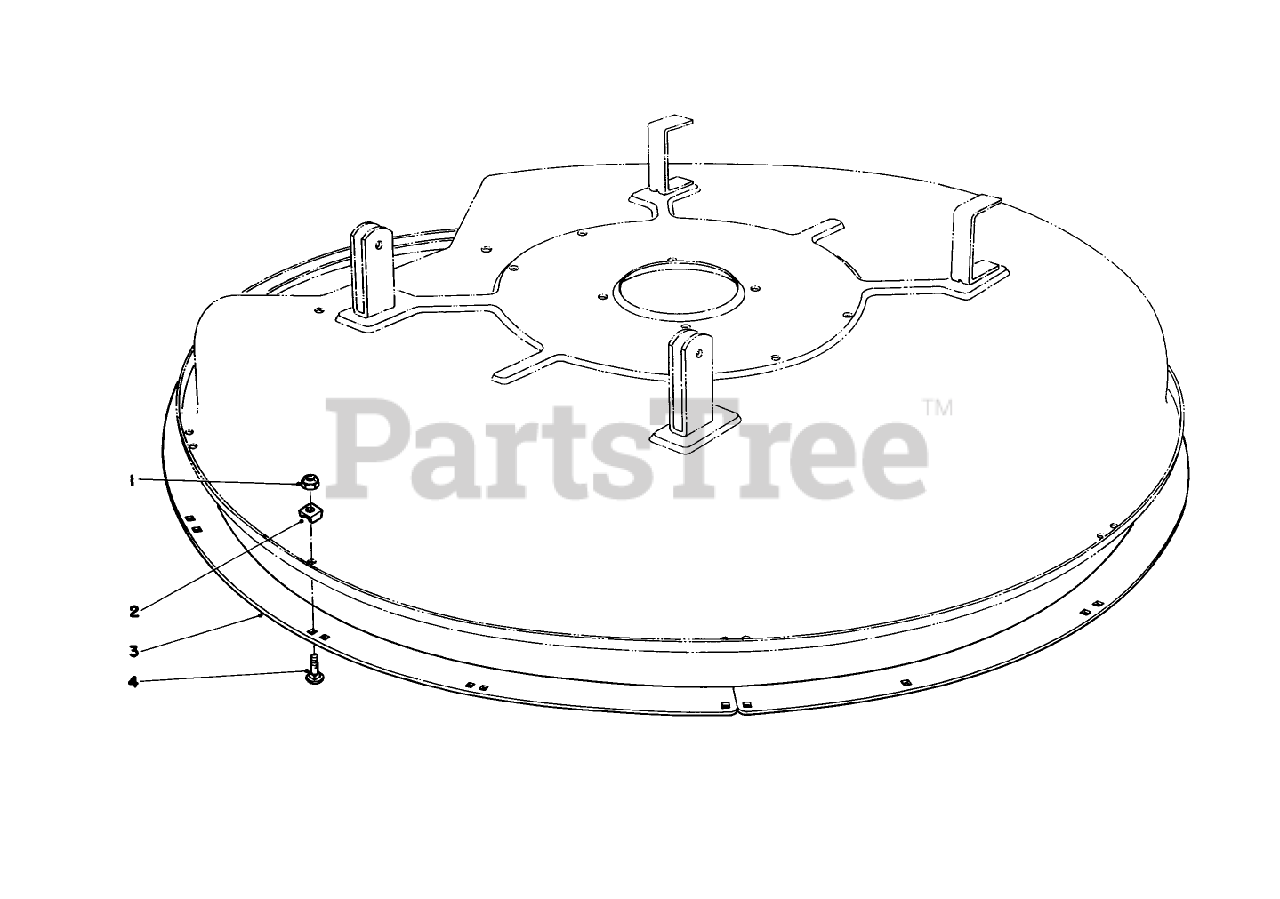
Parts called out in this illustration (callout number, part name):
1	NUT-LOCK, NI
3	DECK RING *B
4	BOLT-CARR
